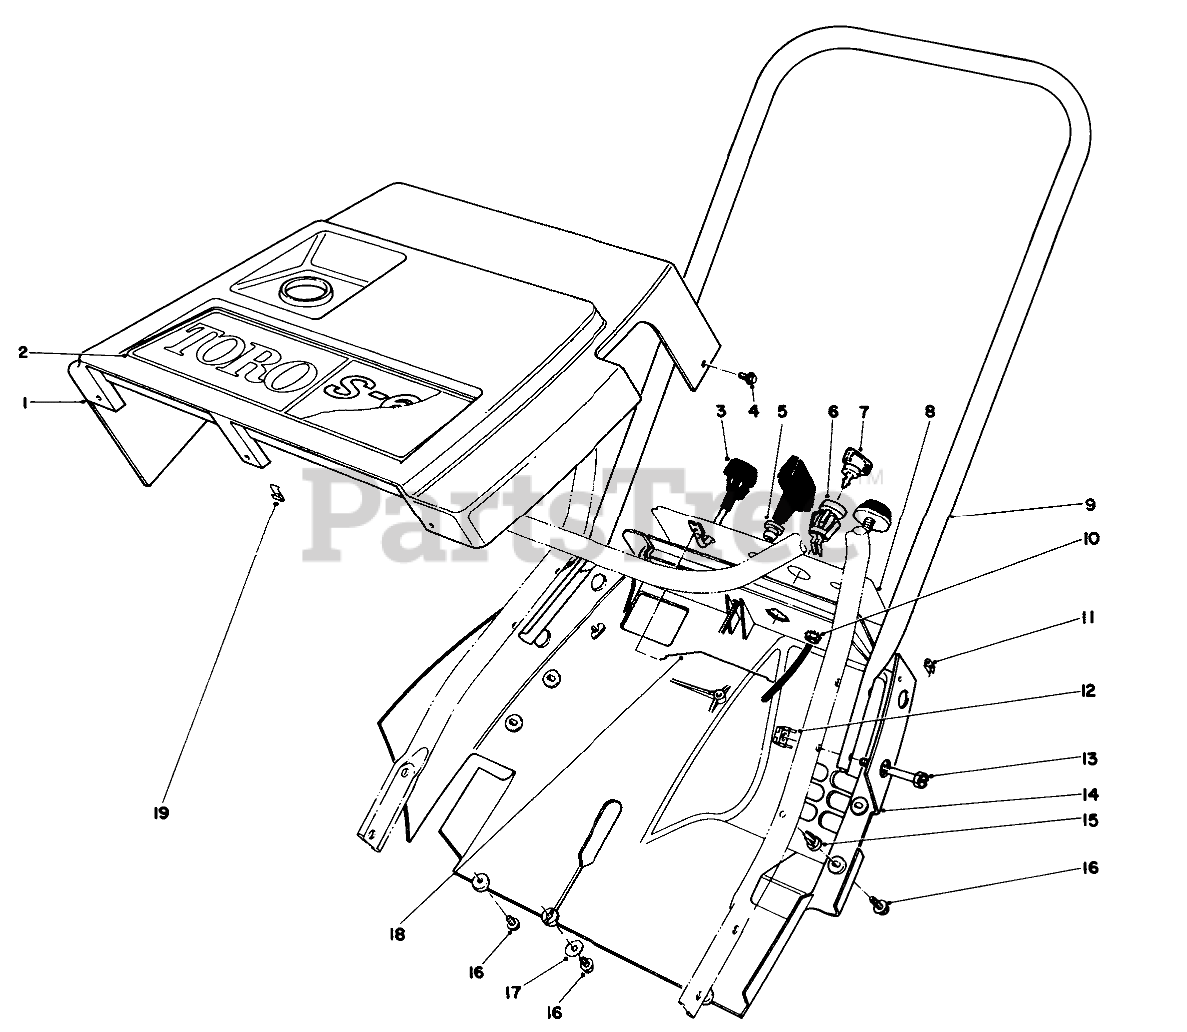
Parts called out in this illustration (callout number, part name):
1	Shroud-Upper
2	TORO DECAL
3	CHOKE CONTROL ASM
4	SCREW-HWHTF
5	GUIDE-ROPE, STARTER
6	SWITCH
7	KEY-IGNITION
8	CONTROL PANEL DECAL
9	UPPER HANDLE ASM
10	NUT-KEPS
12	TINNERMAN NUT
13	SCREW-HEX HD SLOT
14	LOWER SHROUD
15	Nut-Push
16	SCREW-HWHTF
17	WASHER-FLAT
18	CONTROL WIRE
19	NUT "U"
